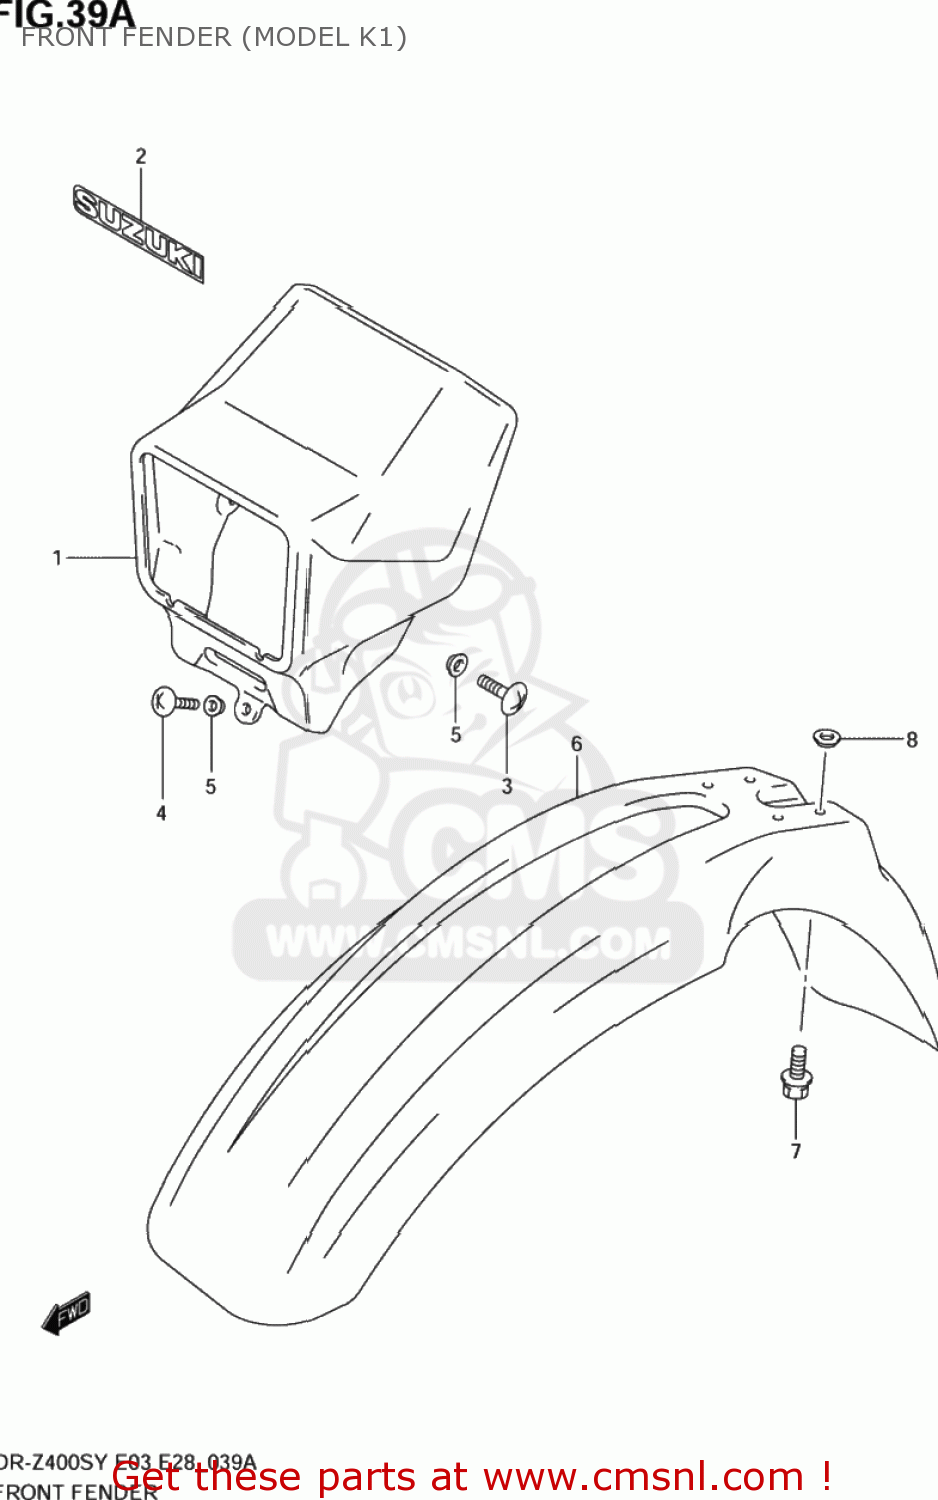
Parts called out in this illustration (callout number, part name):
1	COVER,HEADLAMP
2	EMBLEM,SUZUKI
3	SCREW 6X12
4	SCREW 5X12
5	WASHER
6	FENDER,FR
7	BOLT(6X16)
8	WASHER
